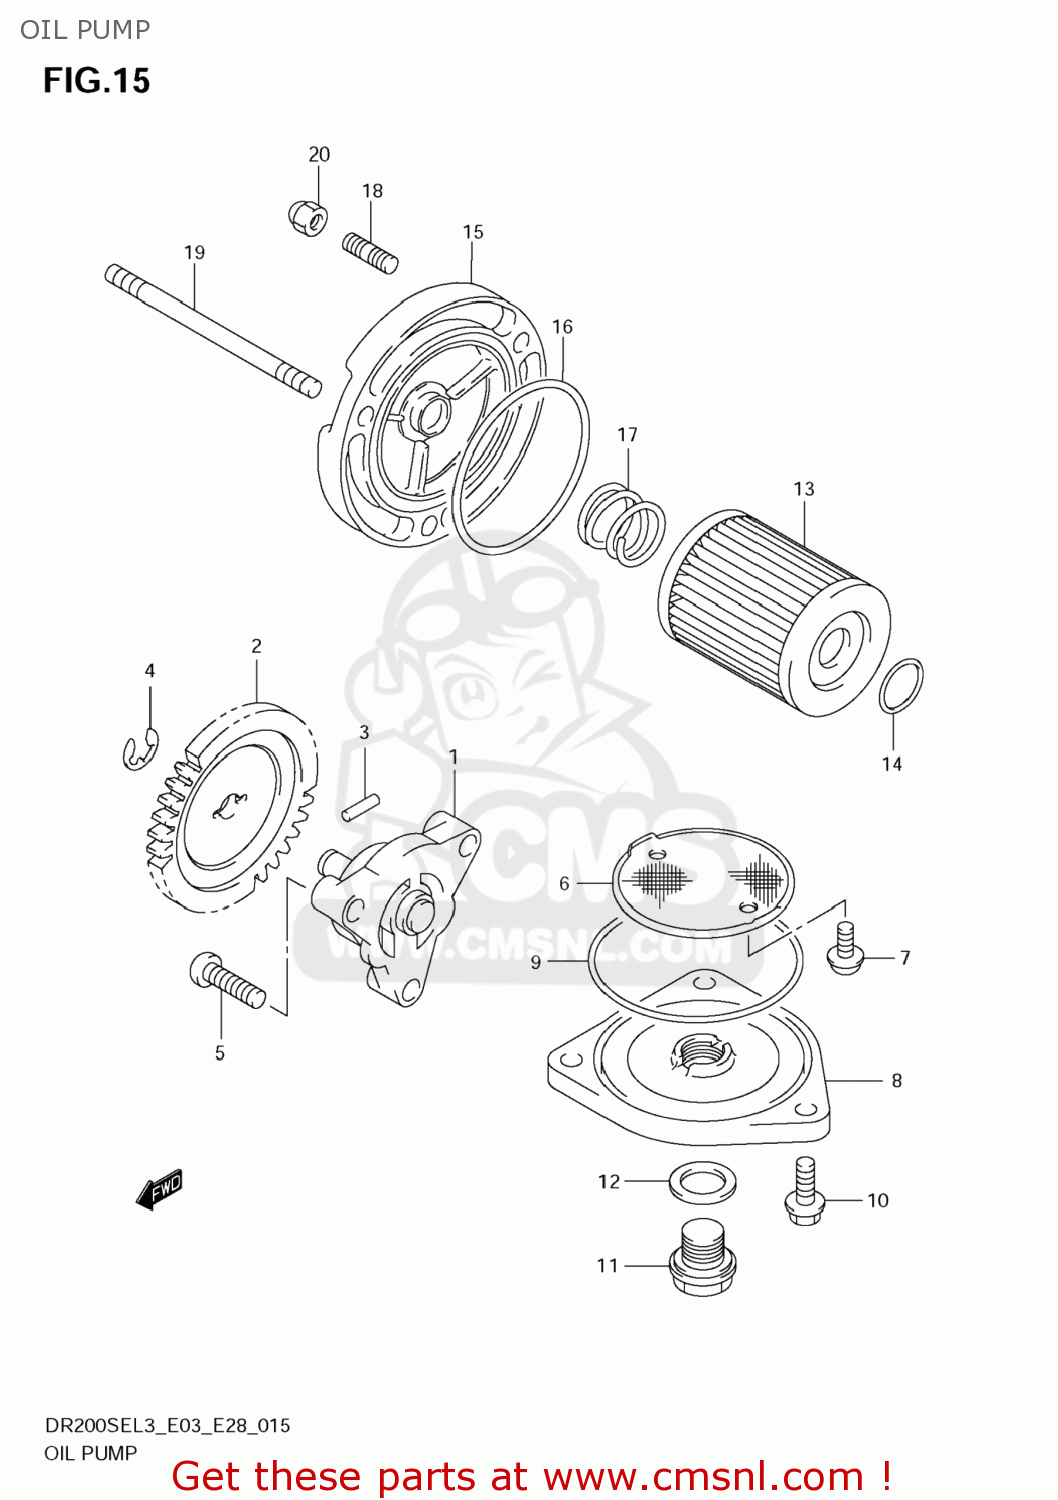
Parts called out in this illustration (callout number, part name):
1	PUMP ASSY,ENGINE OIL
2	GEAR,OIL PUMP DRIVEN
3	PIN(2.5X11.8)
4	E RING
5	SCREW
6	STRAINER,ENGINE OIL
7	SCREW
8	CAP,OIL STRAINER
9	O RING(D:2.4,ID:60.5)
10	BOLT
11	PLUG(14X12)
12	GASKET(13.8X18.8X4.8) (NAS)
13	FILTER ASSY,ENGINE OIL
14	O RING(D:1.9,ID:13)
15	CAP,OIL FILTER
16	O RING(D:2.4,ID:52.6)
17	SPRING
18	BOLT,STUD
19	BOLT,STUD
20	NUT
